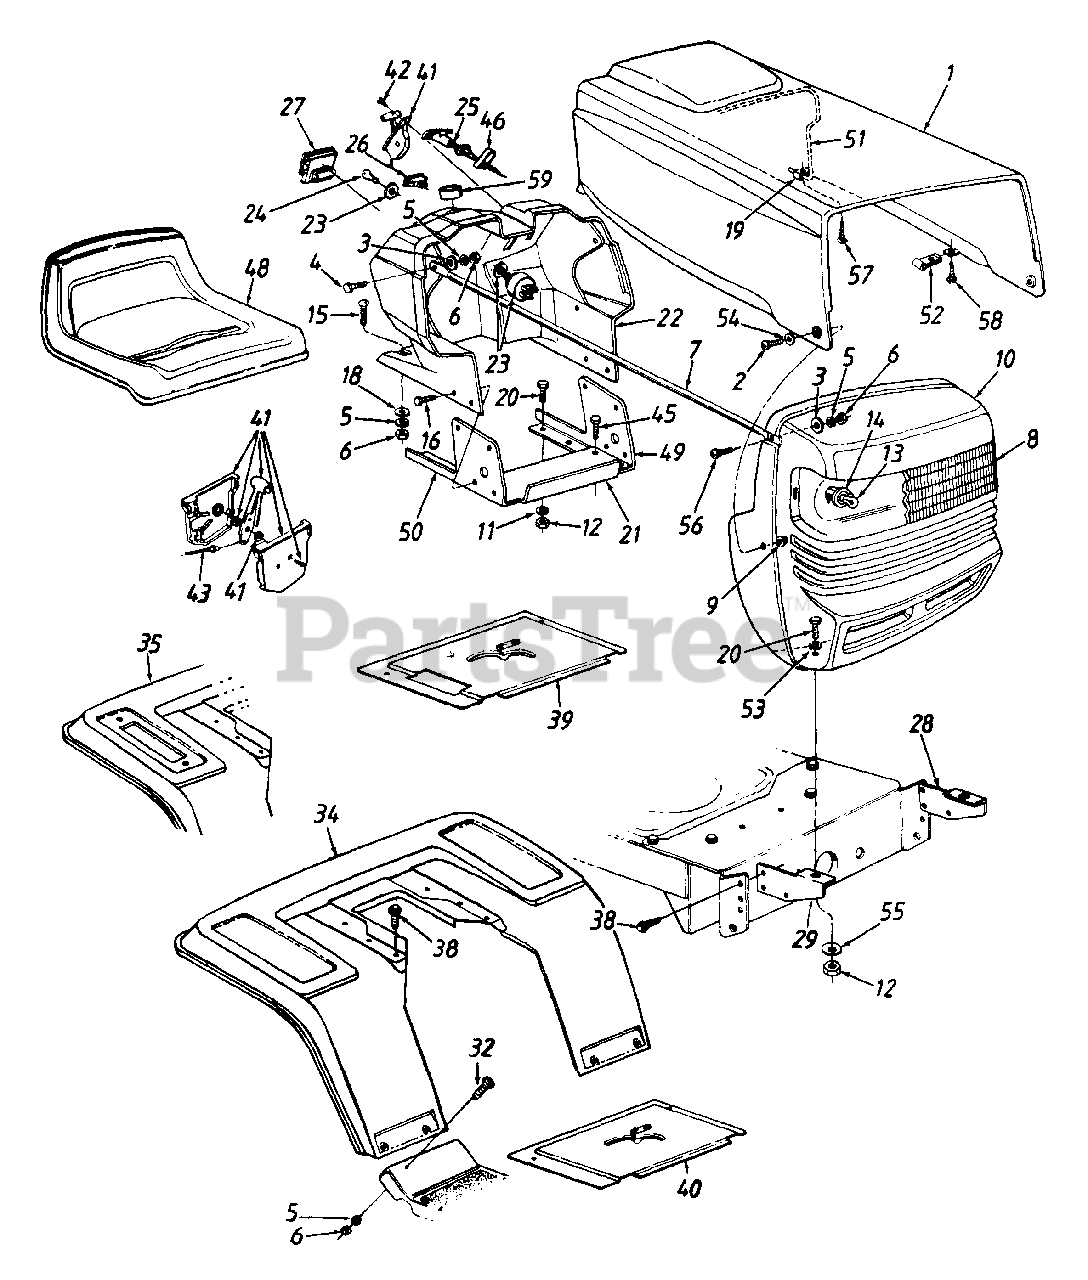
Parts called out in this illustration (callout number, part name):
3	Fl-Wash. .28" I.D. x.75" O.D.
4	Hex Bolt 1/4-20 x .62" Lg."
5	L-Wash. 1/4" I.D.
6	Hex Nut 1/4-20 Thd.
9	Flange L-Nut 1/4-28 Thd.
12	Hex Nut 5/16-18 Thd.
13	Lamp
14	Socket
15	Carriage Bolt 1/4-20 x .75" Lg.
16	Hex Wash. Hd. TT-Tap Scr. 1/4-20 x .5" Lg.
18	Bolt Retainer 1/4" I.D.
19	Speed Nut #10-24 Thd.
20	Hex Bolt 5/16-18 x .75" Lg.
23	Ignition Switch
24	Ignition Key
25	Choke Control
26	Light Switch
27	Ammeter
28	Grille Mtg. Brkt. - L.H.
38	Hex Wash. Hd. AB-Tap Scr. 5/16 x .75" Lg.
39	Shift Cover w/ Cutout
40	Shift Cover
41	Throttle Box Ass'y.
42	Truss Mach. A8-Tap Scr. #10 x .5" Lg.
43	Throttle Control Wire
45	Hex Wash. Hd. B-Tap Scr. 5/16-18 x .5" Lg.
46	Choke Retainer
48	Seat
49	Dash Reinforcement Brkt. - L.H.
50	Dash Reinforcement Brkt. - R.H.
51	Hood Spring
52	Speed Nut #10-16 Thd.
53	Fl-Wash. .344" I.D. x 1" O.D.
54	Spr. Wash. .39" I.D. x .62" O.D.
55	Bell-Wash. .345" I.D. x .88" O.D.
56	Truss Mach. Scr. 1/4-20 x .75" Lg.
57	Pan Hd. Scr. #10-24 x .75" Lg.
58	Truss Mach. B-Tap Scr. #10 x .5" Lg.
59	Steering Column Brg.
